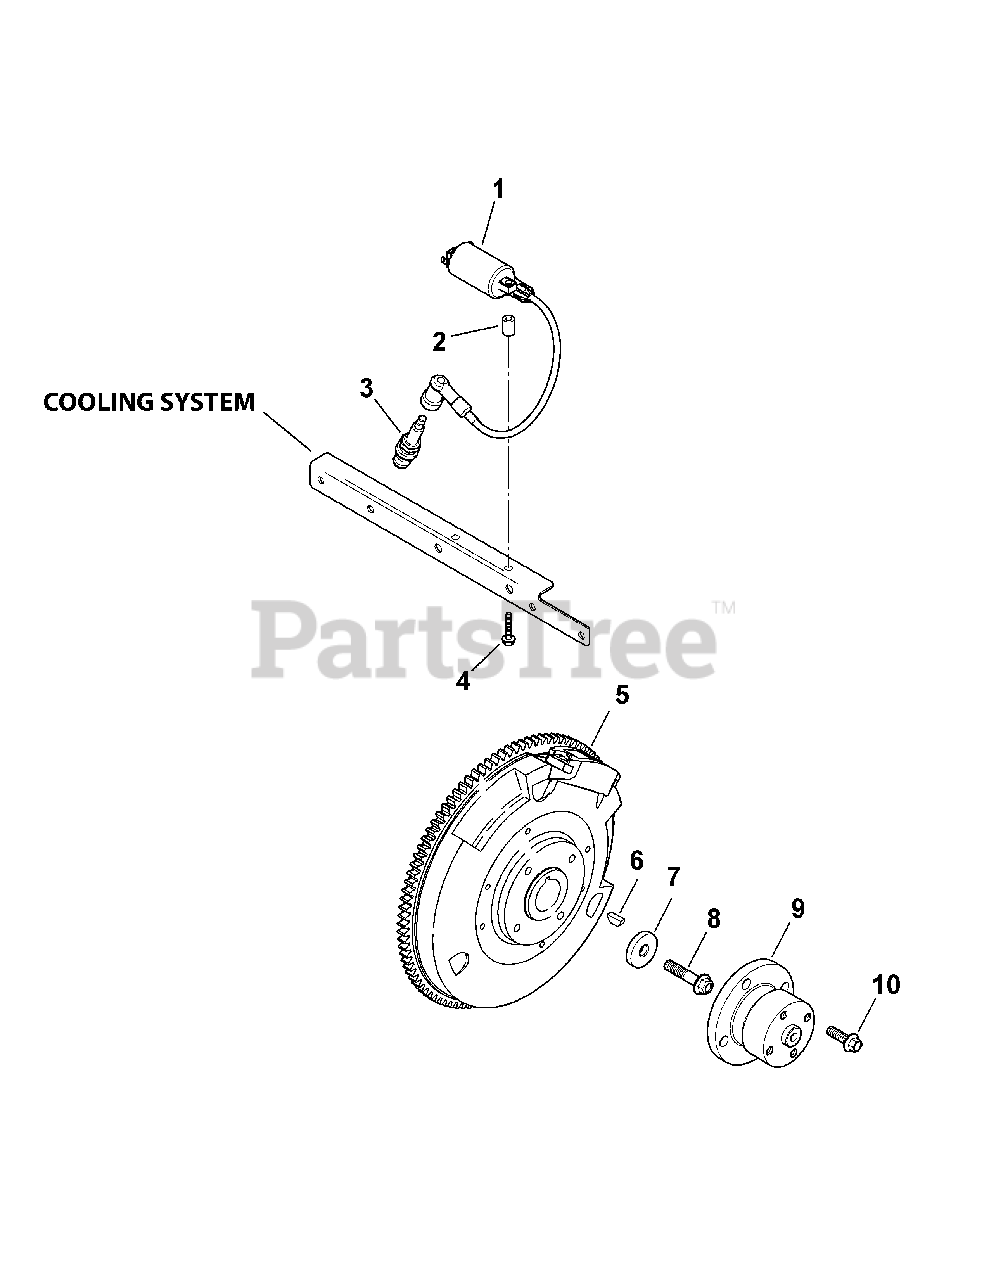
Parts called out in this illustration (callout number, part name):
1	COIL, IGNITION
4	SCREW, THRD FRM M6X1.0X45
5	KIT, FLYWHEEL
6	KEY, 3/16" X 5/8"
7	WASHER, FLAT 13/32"
8	SCREW, FLG M10X1.5X45
9	SHAFT, FRONT DRIVE
10	SCREW, FLG M8X1.25X25
